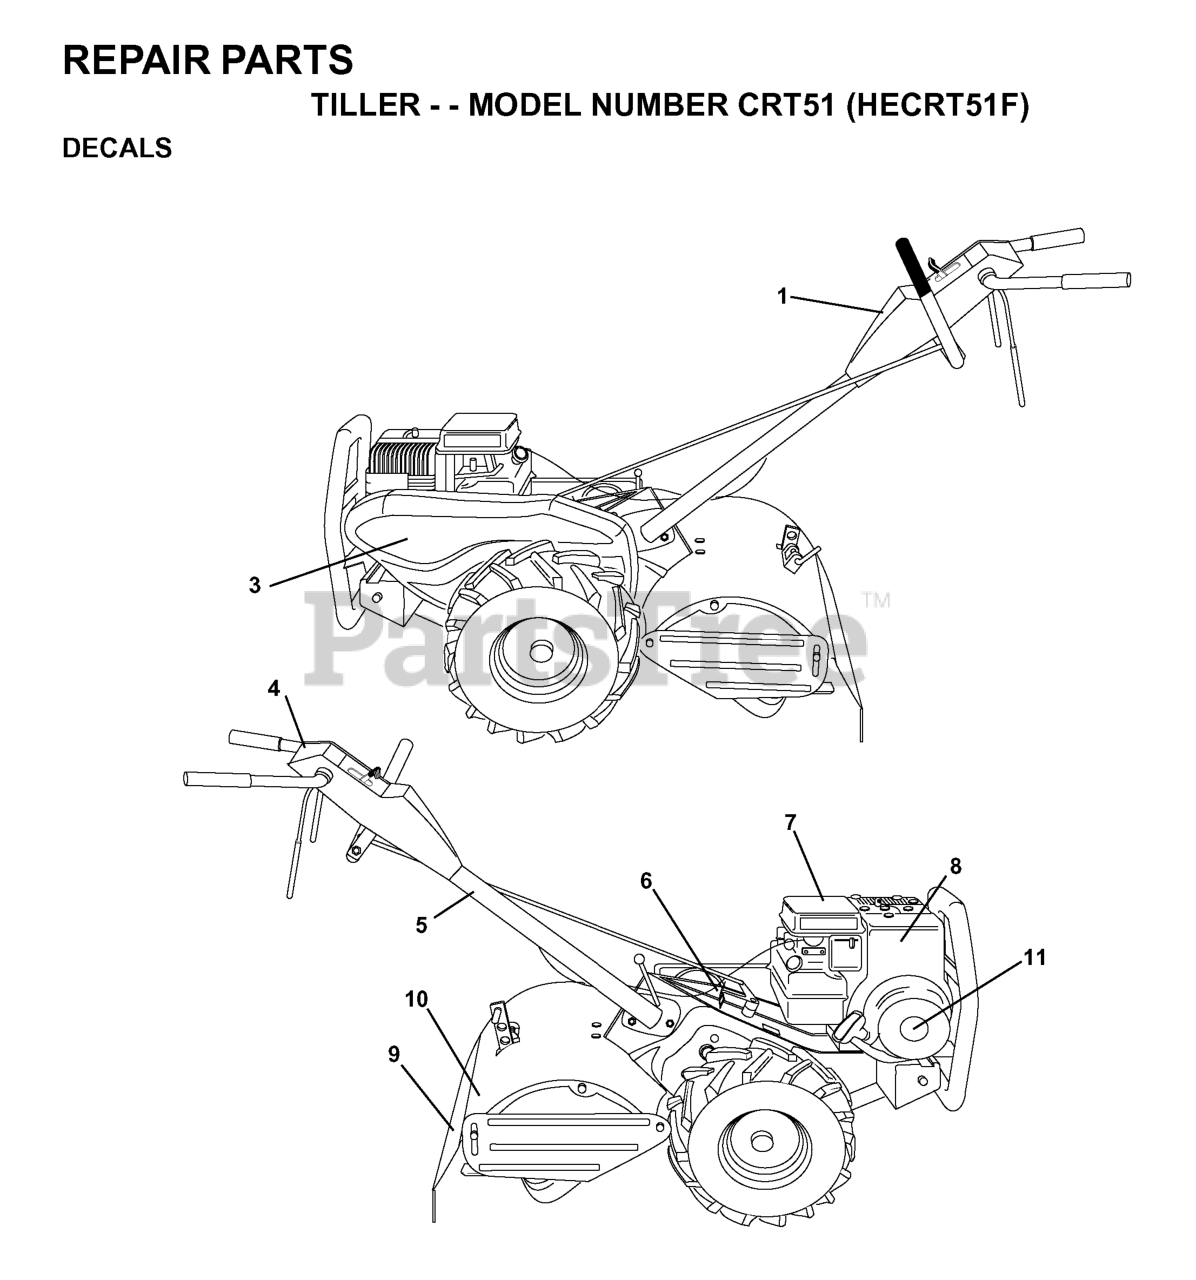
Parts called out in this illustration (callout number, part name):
1	DECAL, LOGO
4	DECAL, LOGO
5	DECAL.PLACEMENT.HAND.SYMBOLS
6	DECAL.SHIFT.INDICATOR.TILLER
8	Decal, Briggs & Stratton
10	DECAL EUROPE STANDARD CE
11	Decal, 5 HP
